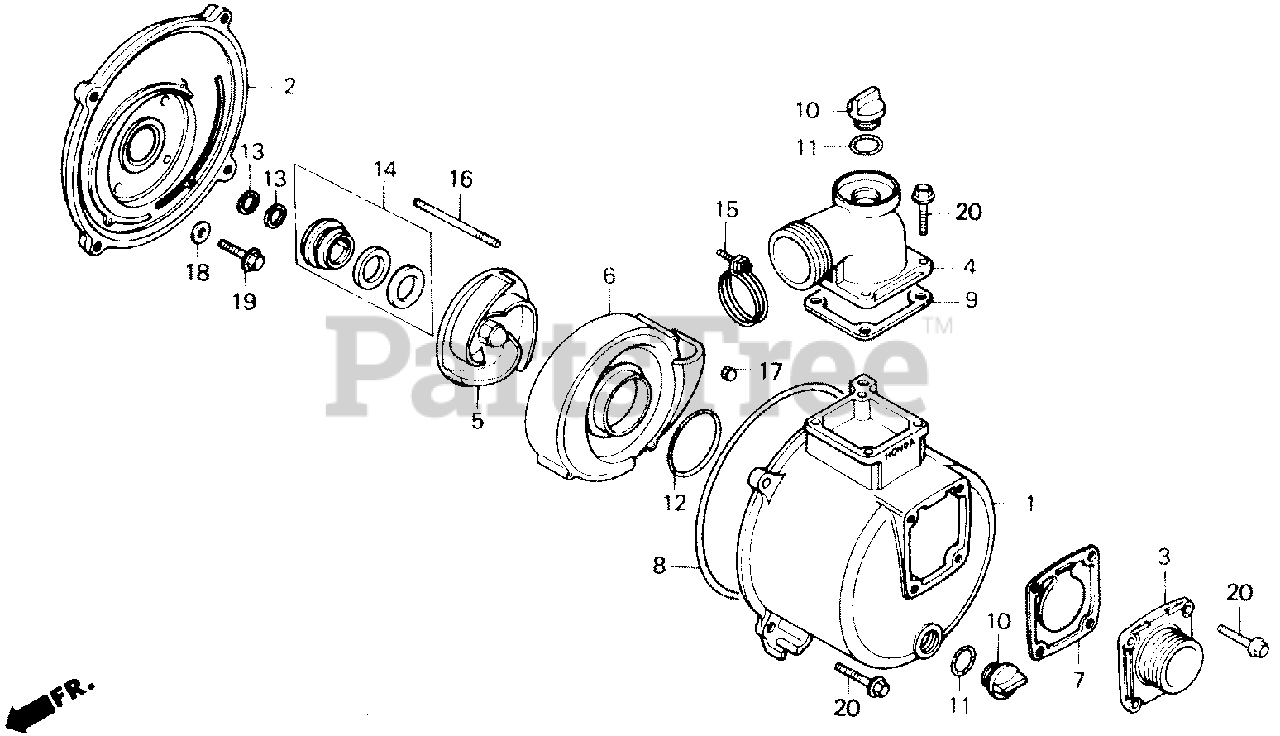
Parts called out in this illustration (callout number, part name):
1	CASING (HONDA) (NOT AVAILABLE)
2	COVER, CASING
3	PIPE, INLET (NPTF)
4	OUTLET (NPTF) (NOT AVAILABLE)
6	CASE, VOLUTE
7	VALVE, IN.
8	RING, CASING SEAL
9	GASKET, OUTLET
10	CAP, FILLER
11	RING, SEAL (B)
12	O-RING (71X5.7)
13	SHIM, ADJUSTER
14	SEAL ASSY., MECHANICAL WATER
15	BAND, HOSE
16	BOLT, STUD (6X50)
17	NUT, CAP (6MM)
18	WASHER, SEALING (8MM)
19	BOLT, FLANGE (8X28)
20	BOLT, FLANGE (10X32)
